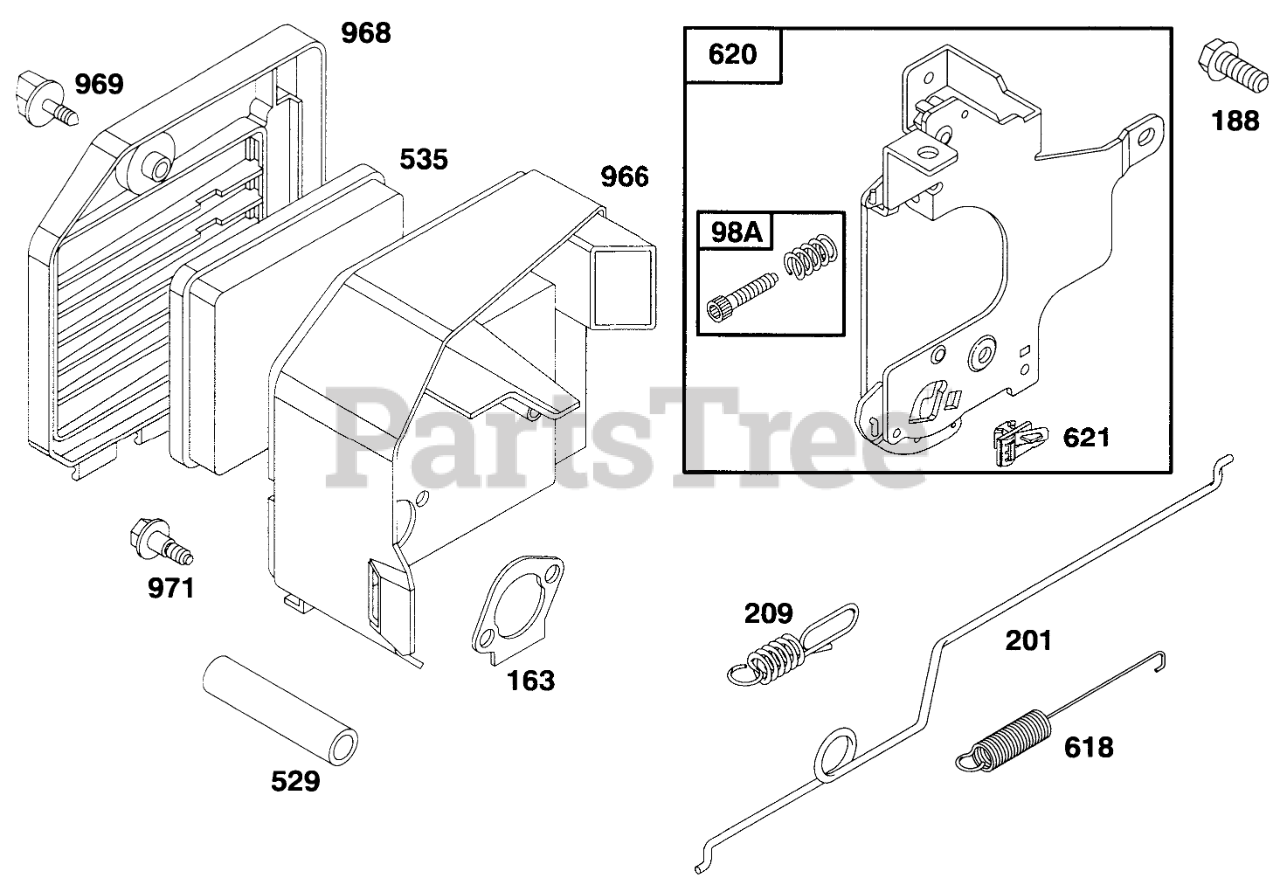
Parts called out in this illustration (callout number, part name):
98A	SPEED ADJUST. SCREW ASM
163	AIR CLEANER GASKET
188	Screw-Cap
201	GOVERNOR LINK
209	GOVERNOR SPRING
529	TUBE - BREATHER
535	FILTER ELEMENT
618	RETURN SPRING
620	CARBURETOR BRACKET
621	STOP SWITCH
966	AIR CLEANER BASE
968	AIR CLEANER COVER
969	AIR CLEANER SCREW
971	AIR CLEANER SCREW
